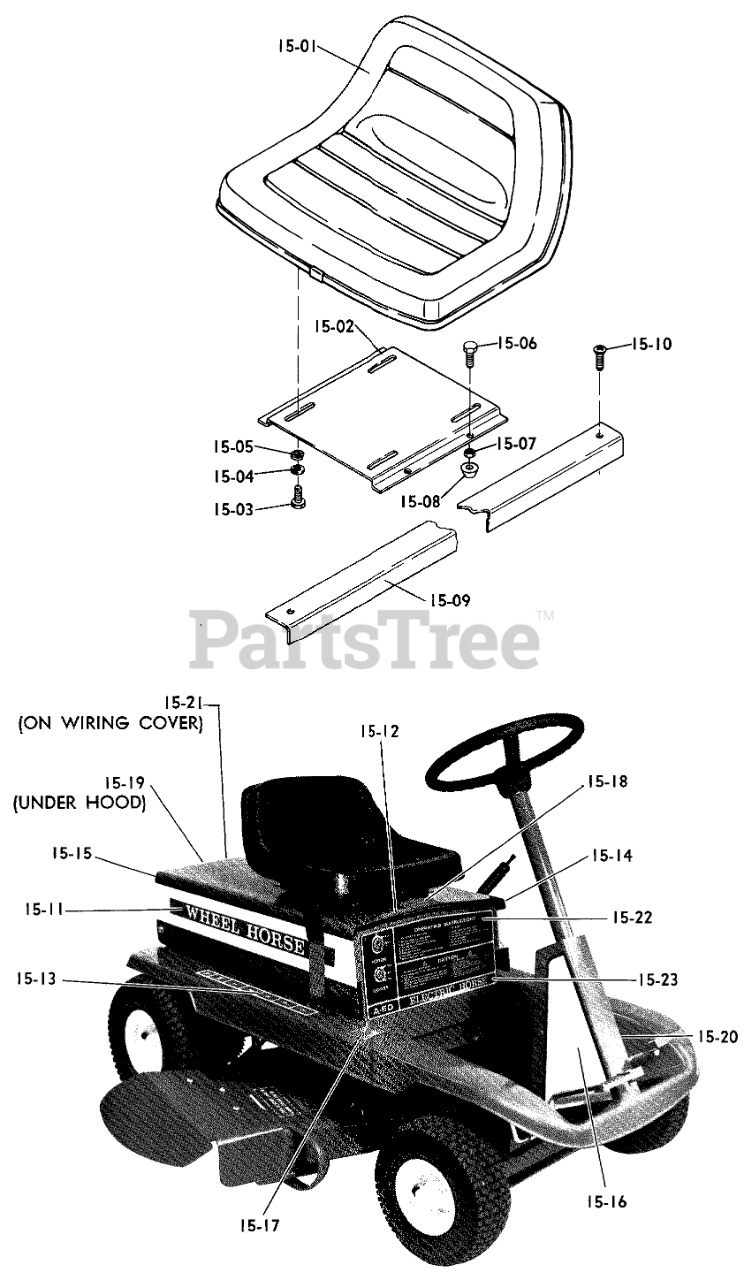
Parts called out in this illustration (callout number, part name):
15-02	Seat Support
15-03	Bolt
15-04	Collar
15-05	Lockwasher
15-06	Bolt 10-32 X 5/8
15-07	Nut, # 10-32 Whizlock
15-08	Bumper
15-09	Seat Support Angle
15-10	Screw, Flat Hd. 1/4-20 x 3/4 Swage Form
15-11	Decal, Wheel Horse, Side Trim
15-12	Decal-Read Manual
15-13	Decal, Shift Pattern
15-14	Decal, Mower Height
15-15	Decal, A-60 Electric
15-16	Decal, Steering Housing R.H.
15-17	Decal, Parking Brake
15-18	Decal, Caution
15-19	Decal, Wiring Diagram
15-20	Decal, Steering Housing L.H.
15-21	Decal, Caution-Disconnect
15-22	Instruction Plate
15-23	Plate Screws
